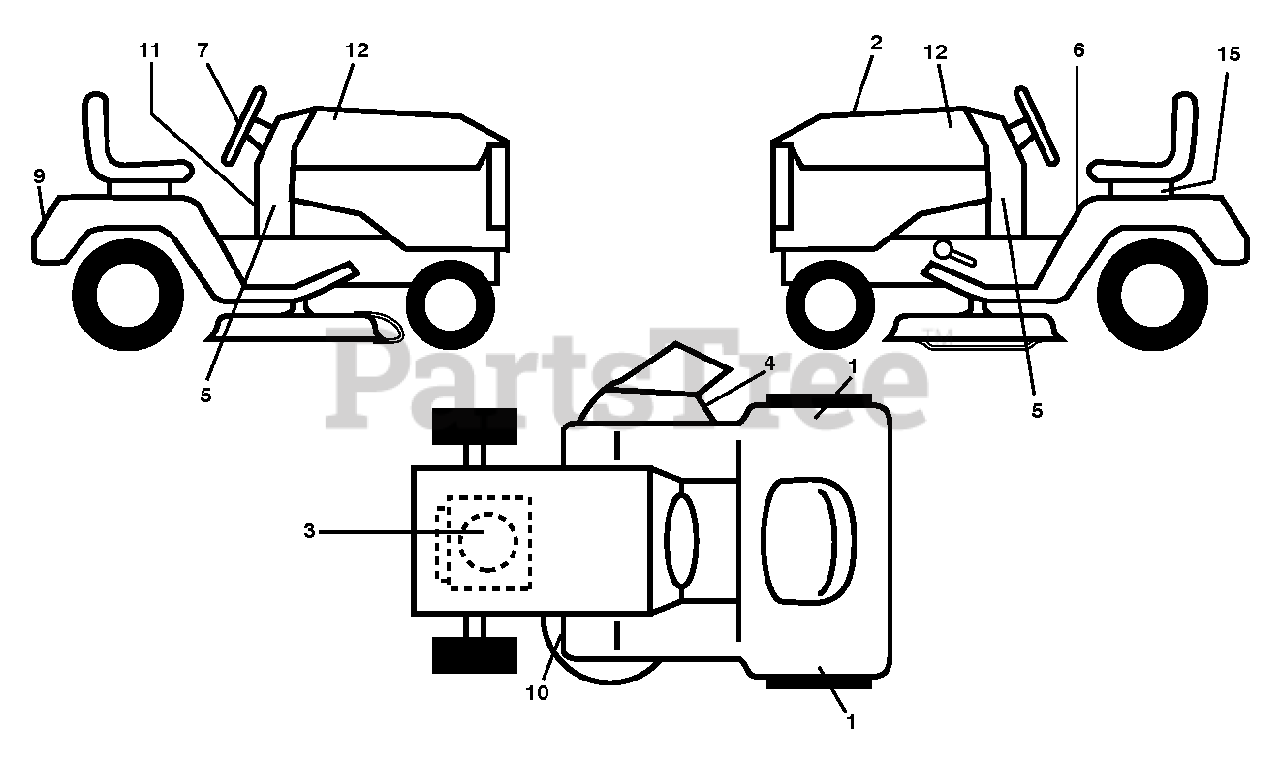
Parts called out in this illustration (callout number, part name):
1	DECAL.FEND.RH/LH.SET.6S.POULAN
2	DCL.RPL.BSM31.INTK.STL.42.PMST
3	DECAL.ENGINE.B&S.(278443)
4	DECAL.WARN.KEEP.HAND.AWAY
6	Fender Warning Decal, English
7	DECAL.WHEEL.STRG.STDHRS.POULAN
9	DECAL.FEND.POULAN.2010
10	DECAL V BELT SCHEMATIC
11	DECAL, WARNING SPARK ARRESTOR
12	DECAL.HOOD.ALPHA.RH/LH.POULAN
15	DECAL BTRY SYMBOLS
